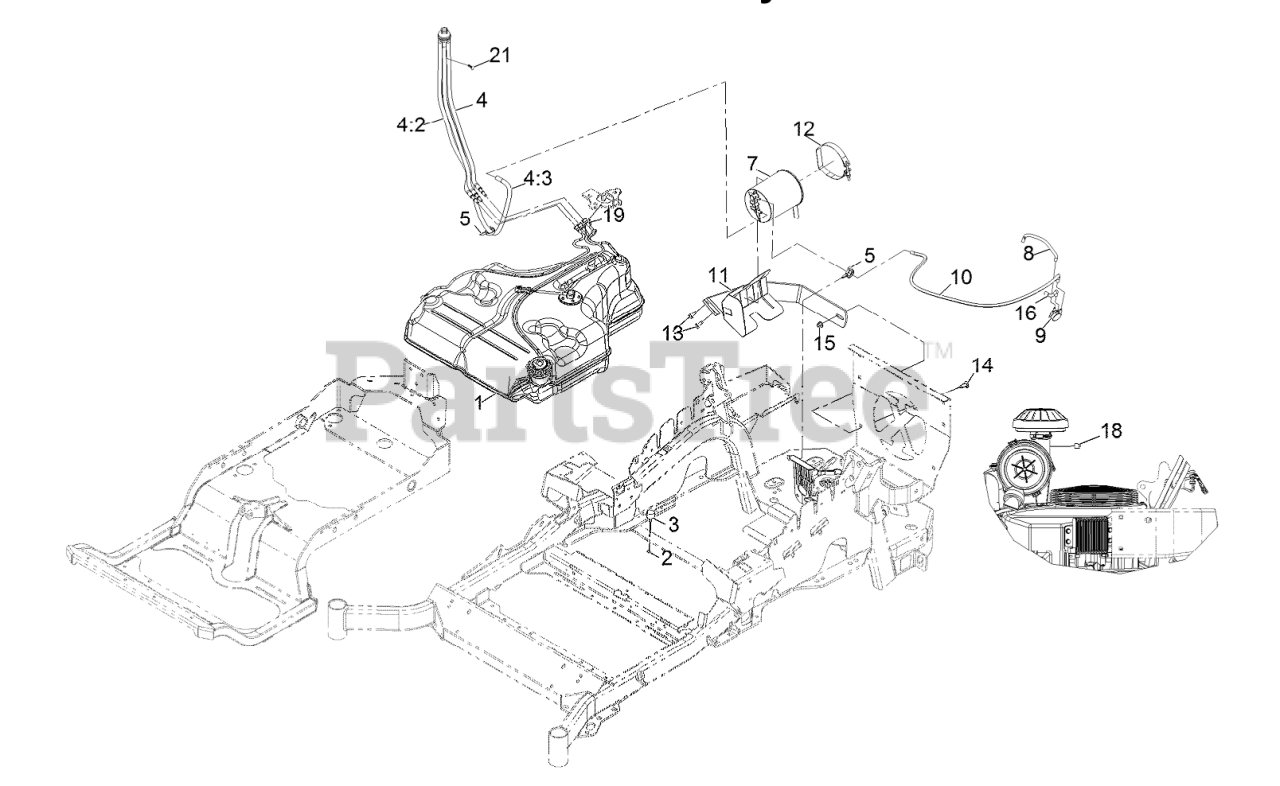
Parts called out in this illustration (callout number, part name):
1	FUEL TANK ASM
2	NUT-JAM
5	FUEL MANIFOLD VENT ASM
5:2	HOSE-FUEL
5:3	HOSE-FUEL
6	PLUG-PLASTIC
8	CANISTER-CARBON, 1200CC
12	MOUNT-CANISTER
13	CLAMP, T-BOLT
14	Screw-HWH 5/16-18 X 3/4 Tf
15	SCREW-CARR
16	NUT-HF, NI
17	TIE-PLASTIC
23	PLUG-PORT
24	CLAMP-HOSE
25	RETAINER-LINE, VAPOR
27	HOSE-FUEL
28	HOSE-FUEL
29	FITTING-STRAIGHT
30	GROMMET
31	BRACKET-VALVE MOUNT
33	SCREW-HHF
34	WASHER-SPRING
35	Hose-Fuel
